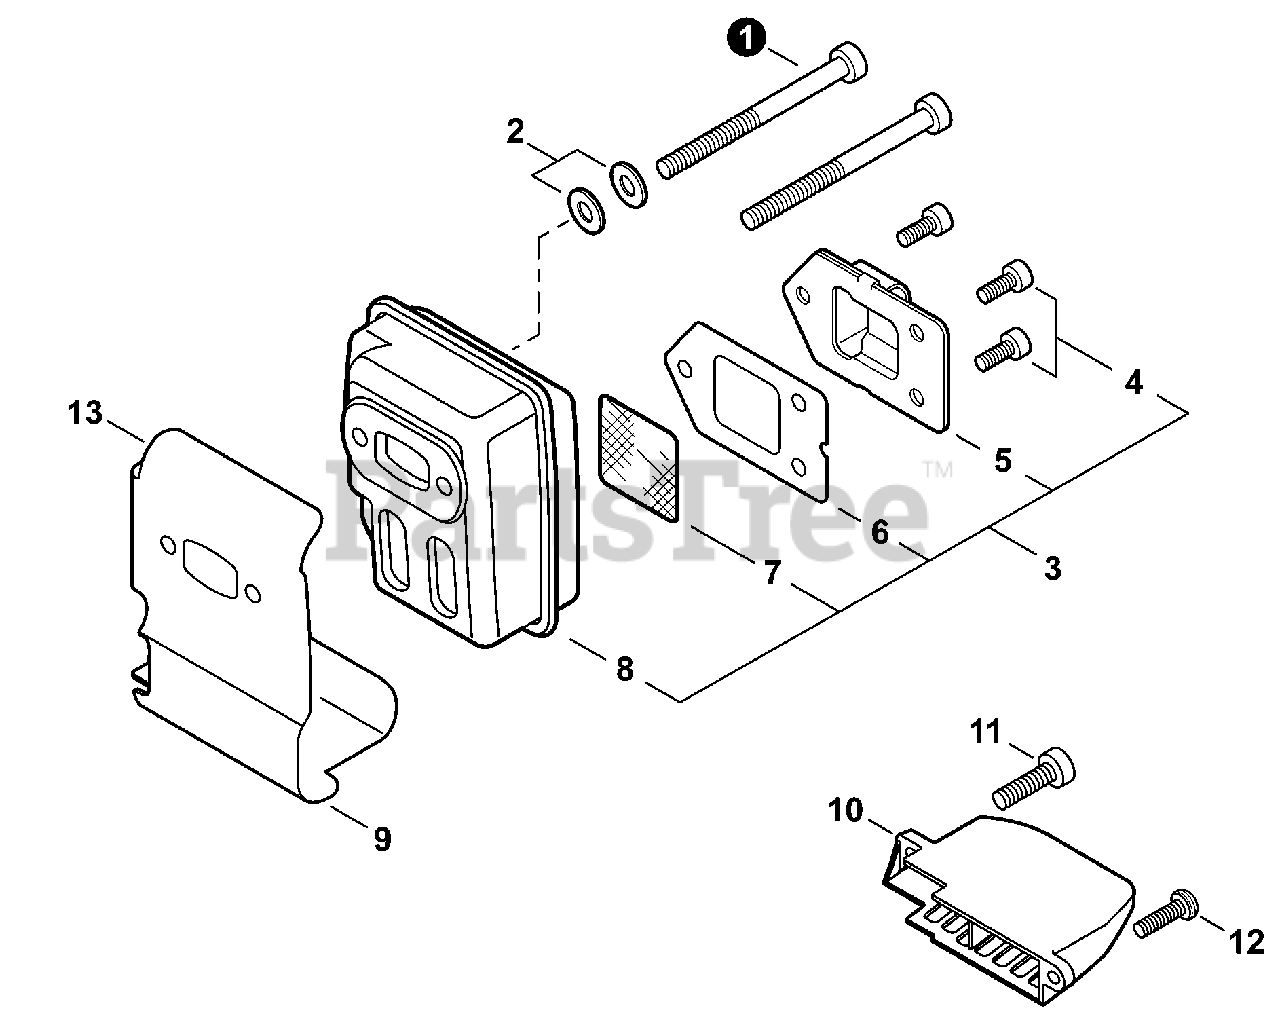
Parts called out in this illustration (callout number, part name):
1	BOLT, TORX 5×55
2	WASHER, FLAT 5.5×10×0.8
3	MUFFLER ASSY
4	BOLT, TORX 4×8
5	GUIDE, EXHAUST
6	GASKET, EXHAUST
7	SCREEN, SPARK ARRESTER
9	HEAT SHIELD, EXHAUST
10	COVER, MUFFLER
11	BOLT, TORX 5×16
12	BOLT, TORX 5×16
13	GASKET KIT: ENGINE, INTAKE, EXHAUST
